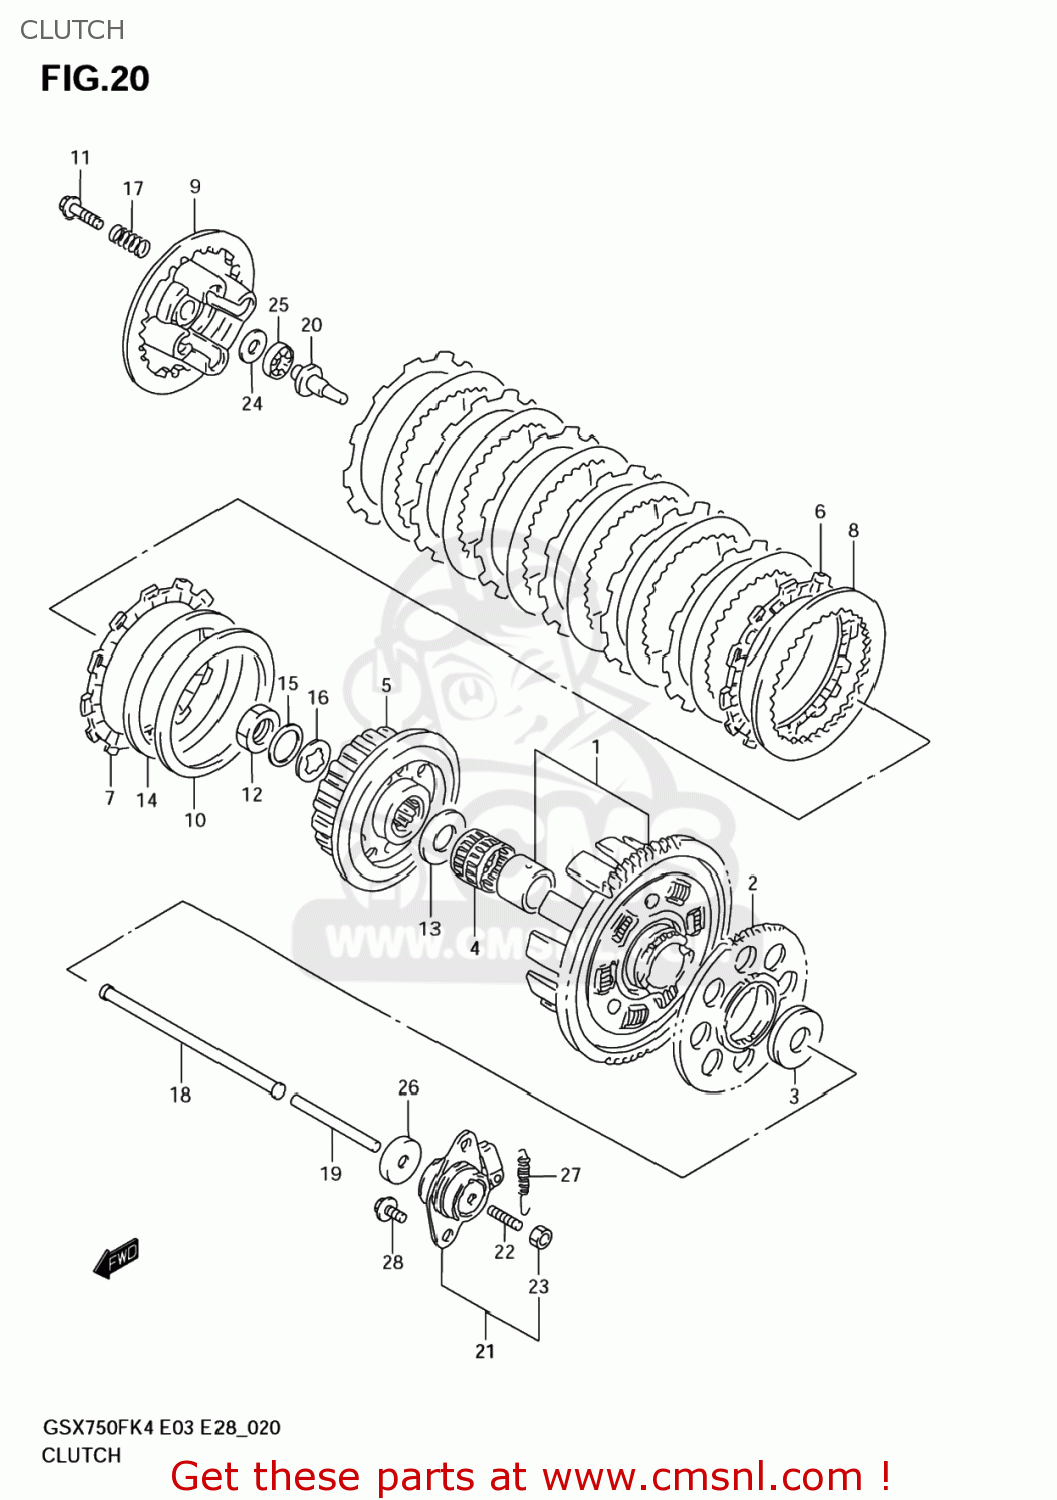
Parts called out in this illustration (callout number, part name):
1	GEAR ASSY,PRI DRIVEN(NT:75)
2	GEAR,GENERATOR DRIVE
3	WASHER(25X54X2.5)
4	BEARING(35X40X35.8)
5	HUB,CLUTCH SLEEVE
6	PLATE,CLUTCH DRIVE (NAS)
7	PLATE,CLUTCH DRIVE(T:3.5) (NAS)
8	PLATE,CLUTCH DRIVEN (NAS)
9	DISC,CLUTCH PRESSURE
10	SEAT,WAVE WASHER(T:1.4)
11	BOLT(6X25)
12	NUT
13	WASHER(25X50X2.5)
14	WASHER
15	WASHER
16	SHIM(22X36X1)
17	SPRING
18	ROD,CLUTCH PUSH,R
19	ROD,CLUTCH PUSH,L
20	PIECE,CLUTCH PUSH
21	SCREW ASSY,CLUTCH RELEASE
22	SCREW(6X25)
23	NUT
24	WASHER(15.5X28X1)
25	BEARING(15X28X2)
26	SEAL,OIL(6X34X5.5)
27	SPRING
28	BOLT
